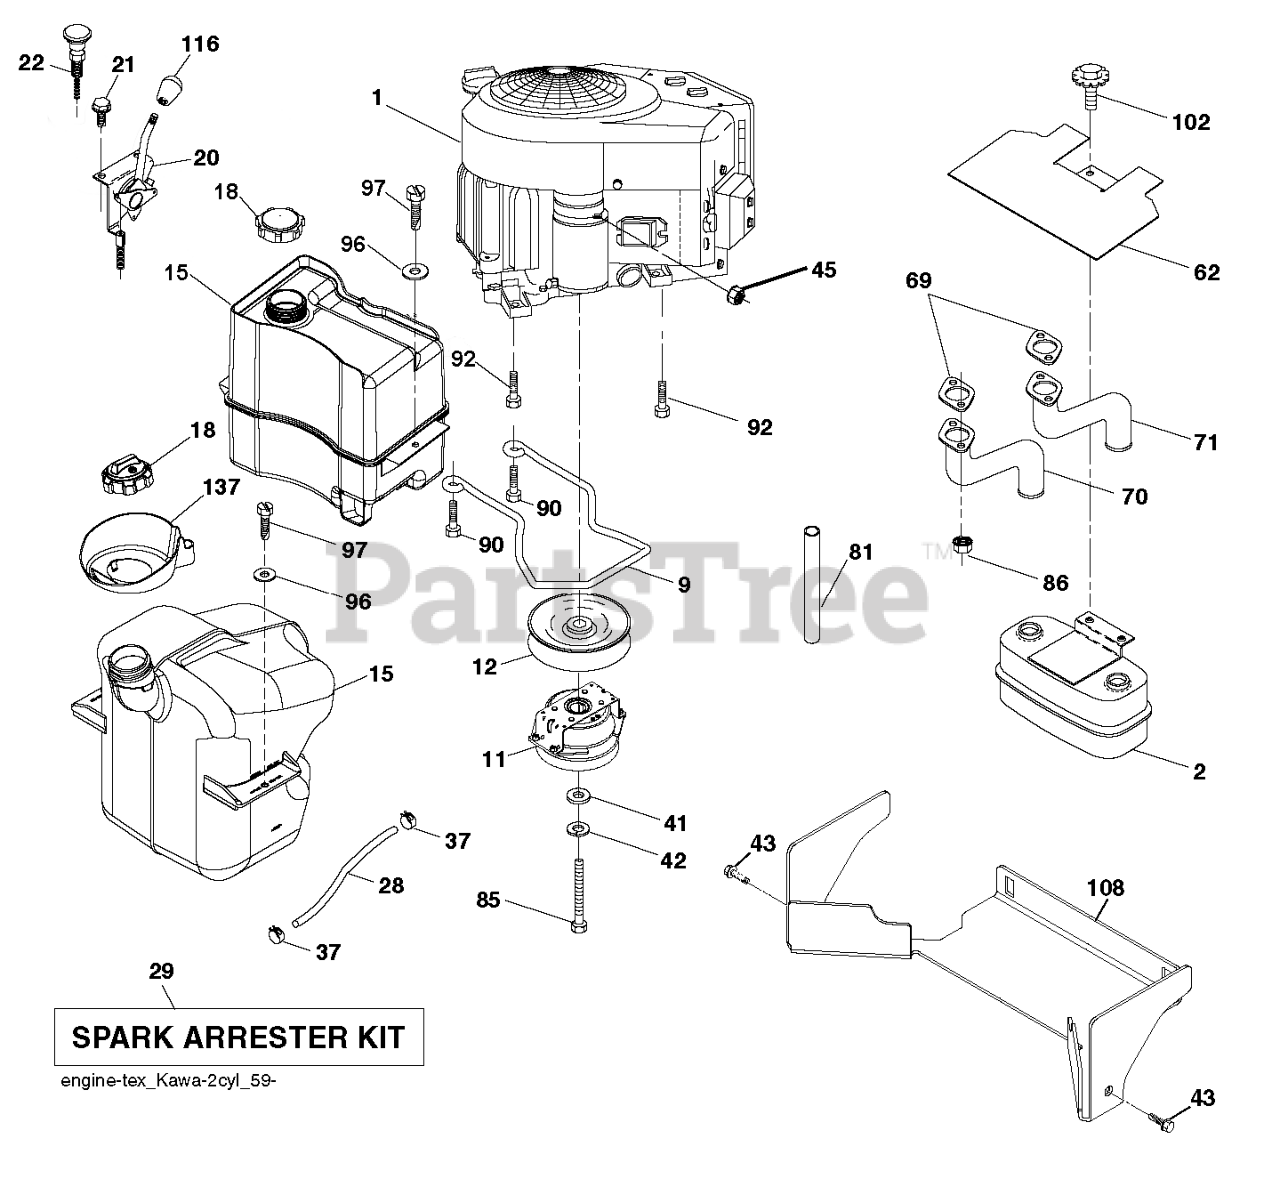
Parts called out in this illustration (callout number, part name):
2	MUFFLER.ASM.TWIN.MNTG.BRACKET
11	CLUTCH MAGNETIC CLUTCH & BRAKE
12	PULLEY.ENGINE.TUFFTORQ
15	TANK.ASSY.XTERNAL.FILL.GT2.TEX
15	TANK.ASSEMBL.2.5GAL.NON-EPA
18	CAP.ASM.FUEL.2.25"TOP.TURN
18	CAP.2.25'.VENTED.RATCHET.EPA
20	CONTROL.THROTTLE.PRO.
22	CONTROL.CHOKE.ERGO.BLACK
28	HOSE 1/4" LOW PERMEATION FUEL
29	KIT.SPARK ARRESTOR 794945 B&S
37	HOSE CLAMP
43	BOLT.5/16-18UNCX3/4 W/SEMS.BLK
62	SERVICE KIT HEAT SHIELD
70	TUBE.EXHAUST.LH.FR961/FR730
71	TUBE.EXHAUST.RH.FR961/FR730
81	TUBE, DRAIN OIL ASM.
85	BOLT.HEX.7/16-20X3.75.GR5.RED
86	NUT.HEX.FLANGE.TOPLOCK
90	SCREW 3/8-16X1
92	SCREW 3/8-16X1
97	SCREW HEXWSHR 1/4-20X3/4
102	BOLT.HEX.HD.WASHER.5/16-18X.75
108	SHIELD.CLUTCH.BLACK.MS431
116	KNOB - SHIFT
137	SPILL.CUP
